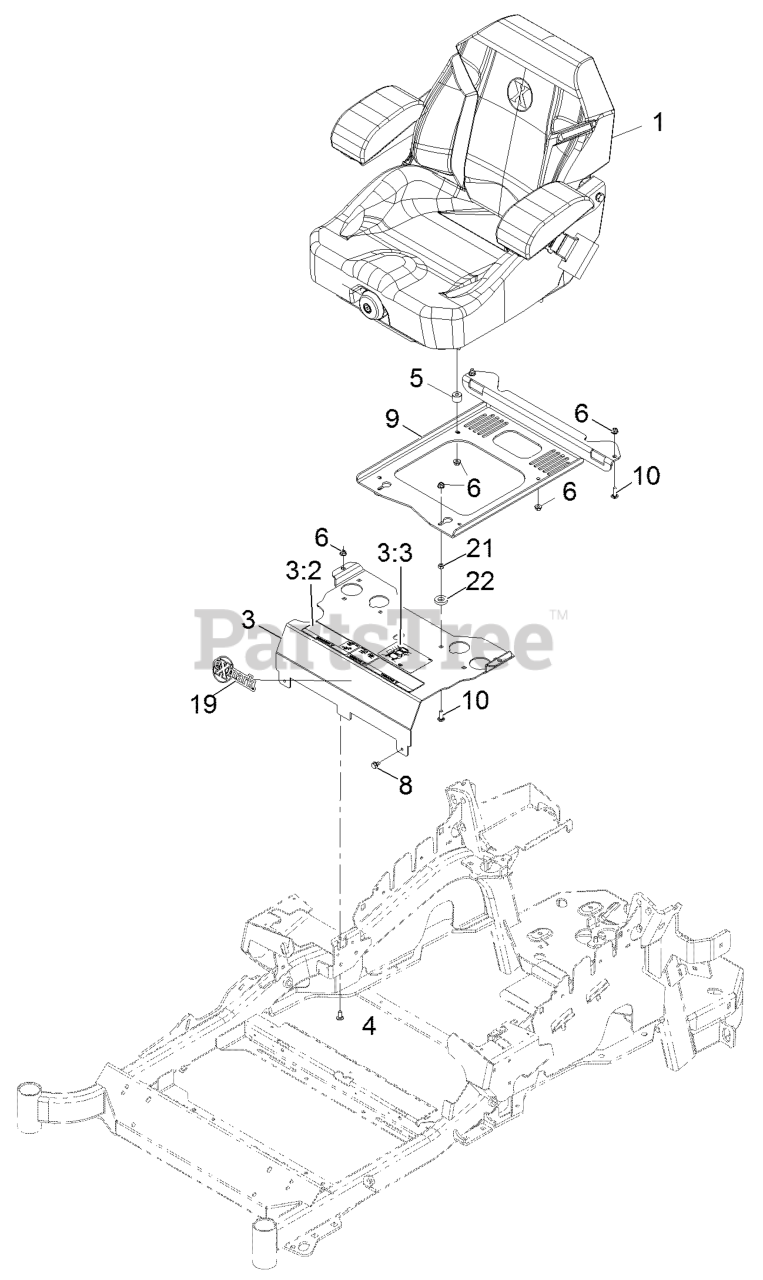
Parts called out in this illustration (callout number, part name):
1	KIT-SUSPENSION SEAT
3	MOUNT-SEAT
3:2	DECAL-CONSOLE
3:3	DECAL-SERVICE AID
4	SCREW-CARR
6	NUT-HF, NI
9	PLATE-SUPPORT, SEAT
10	SCREW-CARR
21	NUT-HEX
